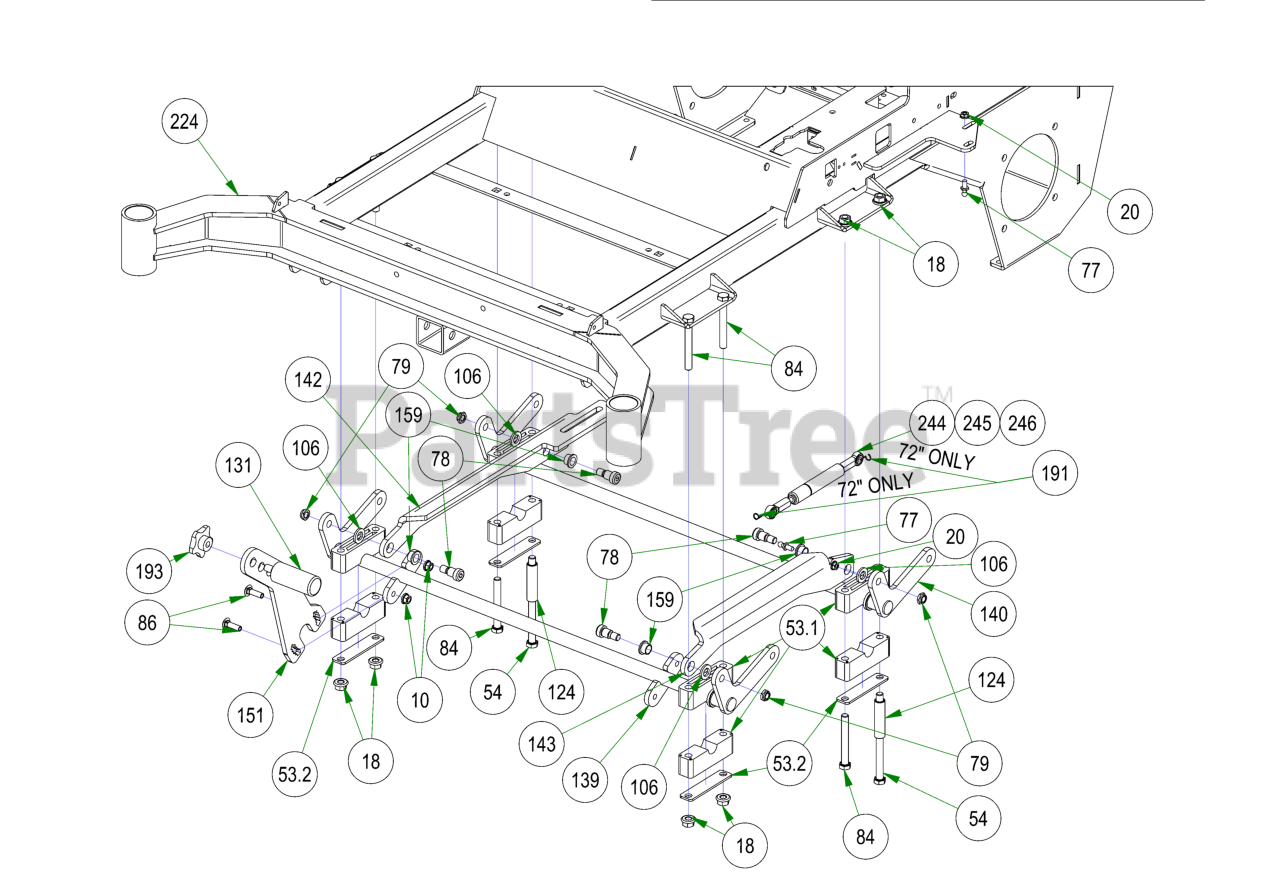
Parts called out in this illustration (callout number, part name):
5	.625 ID x 1.250 OD x .062 THK F/W Nylon
10	3/8-16 NYLON INSERT FLANGE LOCKNUT (GR.F) ZINC
11	1/2-13 HEX SERRATED FLANGE NUT HARD/ZINC
14	1/2-13 HEX NUT ZINC
18	1/2-13 NYLON INSERT FLANGE LOCKNUT ZINC
19	1/4-20 HEX SERRATED FLANGE NUT HARD/ZINC
20	5/16-18 HEX SERRATED FLANGE NUT HARD/ZINC
53	Pillow Block Assembly
53.1	Two Piece Pillow Block
53.2	Two Piece Pillow Block Strap
54	1/2-13 X 7 HEX CAP SCREW (GR.5) ZINC
59	2 1/2 x 1/2 Carriage Bolt
77	10mm Damper Ball Stud-XP Linkage
78	5/8 X 5/8 SOCKET SHOULDER BOLT ZINC YELLOW
79	1/2-13 NYLON INSERT JAM LOCKNUT ZINC
81	1/4-20 X 1-1/4 HEX CAP SCREW (GR.5) ZINC
84	1/2-13 X 4 HEX CAP SCREW (GR.8) ZINC YELLOW
86	3/8-16 X 1-1/4 CARRIAGE BOLT ZINC
101	.517 SQ WDTH ID X .937 OD X .060 THICK F/W PHOS/OIL
106	.635 ID X 1.120 OD X .140 THICK FLAT WASHER NYLON
115	.505 ID X 1.000 OD X .125 THICK FLAT WASHER NYLON
120	5/8" Split Collar
122	MZ Deck Idler Spacer
124	2019 Deck Stop Spacer
131	Knurled Pedal
137	Dial Rod Plunger
138	2019 Outlaw Gen2 Deck Height Dial Rod Assy
138.1	3/8-24 Nylon Insert jam locknut
138.2	3/8" Flat Washer
138.3	2019 Deck Height Cam
138.4	2019 Outlaw Gen2 Dial Rod
139	2019 Outlaw Actuator - Front
140	2019 Outlaw Actuator - Rear
142	2019 Actuator Linkage – Right – Black
143	2019 Actuator Linkage - Left - Black
151	Foot Lift Upright Lever
154	2019 Outlaw Deck Travel Lock
159	.627 ID X .753 OD X .500 LGTH X 1.000 FLG OD X .094 FLG THICK FLANGED BEARING OIL-IMPREG BRNZ
165	Brake Spring
190	Seat Bracket Pin
191	Security Ring - PC744
193	Foot Pedal Knob 1/2-13
221	Travel Lock Rubber Grip
224	2023 Rebel Frame - Painted
244	200 lb Gas Spring- 54" Deck outlaw
245	250lb Gas Spring - 61" Deck
246	300lb Gas Spring - 72" Deck
